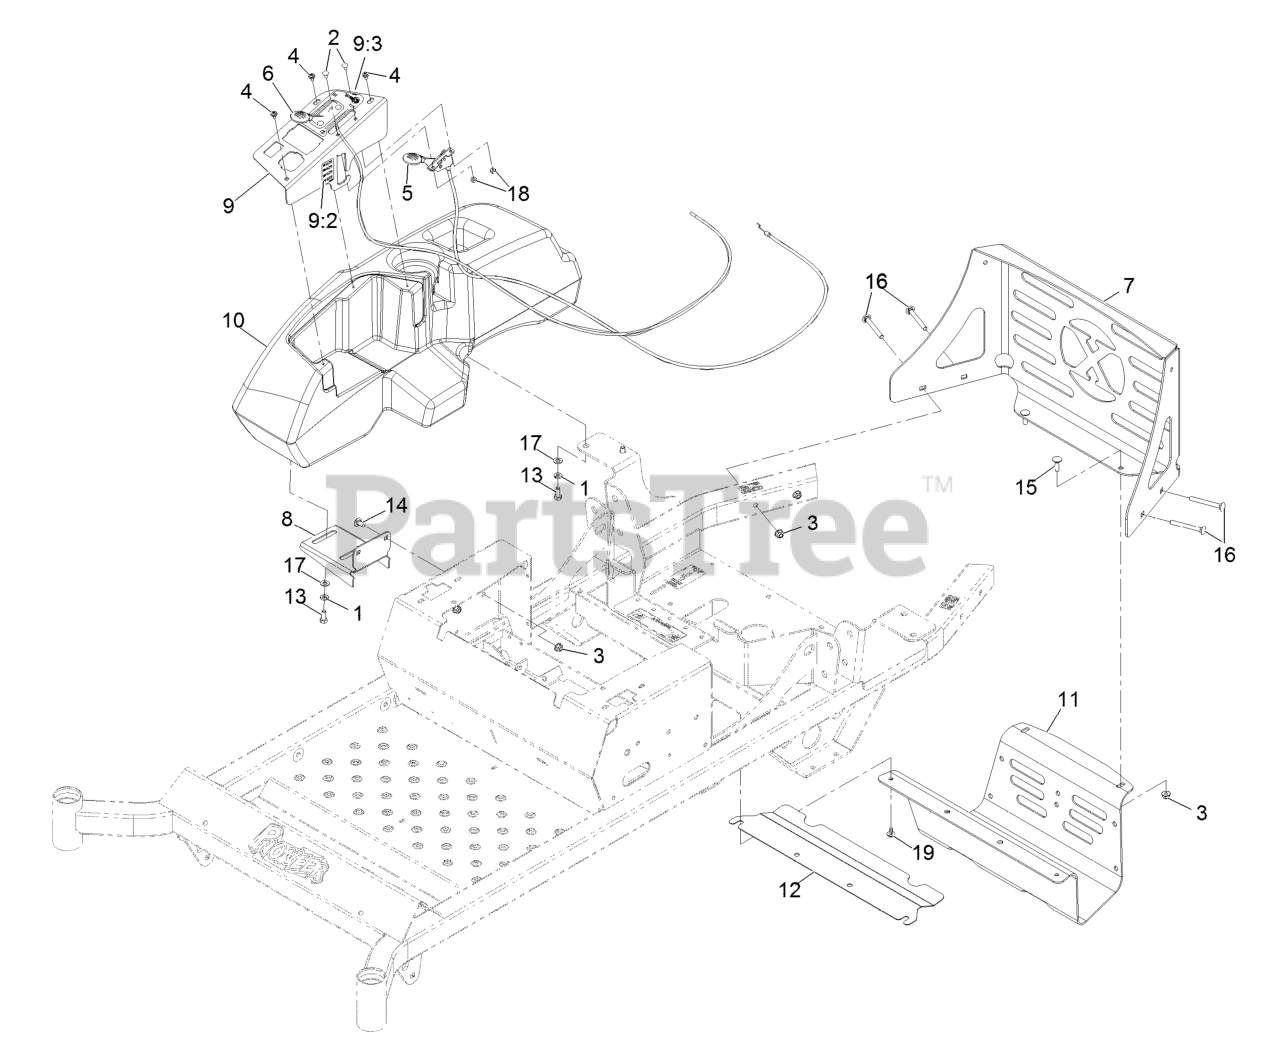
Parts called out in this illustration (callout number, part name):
1	WASHER-LOCK
2	BOLT-CARR
3	NUT-HF, NI
4	SCREW-PPH
5	CONTROL-THROTTLE
6	CONTROL-CHOKE
7	PANEL,REAR GUARD
8	BRACKET-TANK AND FENDER
9	ASM, CONTROL PANEL W/ DEC
9:2	DECAL,FUSE BLOCK
9:3	DECAL-THROTTLE CHOKE
10	CONSOLE,RH
11	GUARD-MUFFLER
12	SHIELD, HEAT
13	SCREW-HH
14	SCREW-CARR
15	BOLT-CARR
16	SCREW-CARR
17	WASHER-PLAIN
18	NUT-LOCK, NI
19	SCREW-HHFTF
